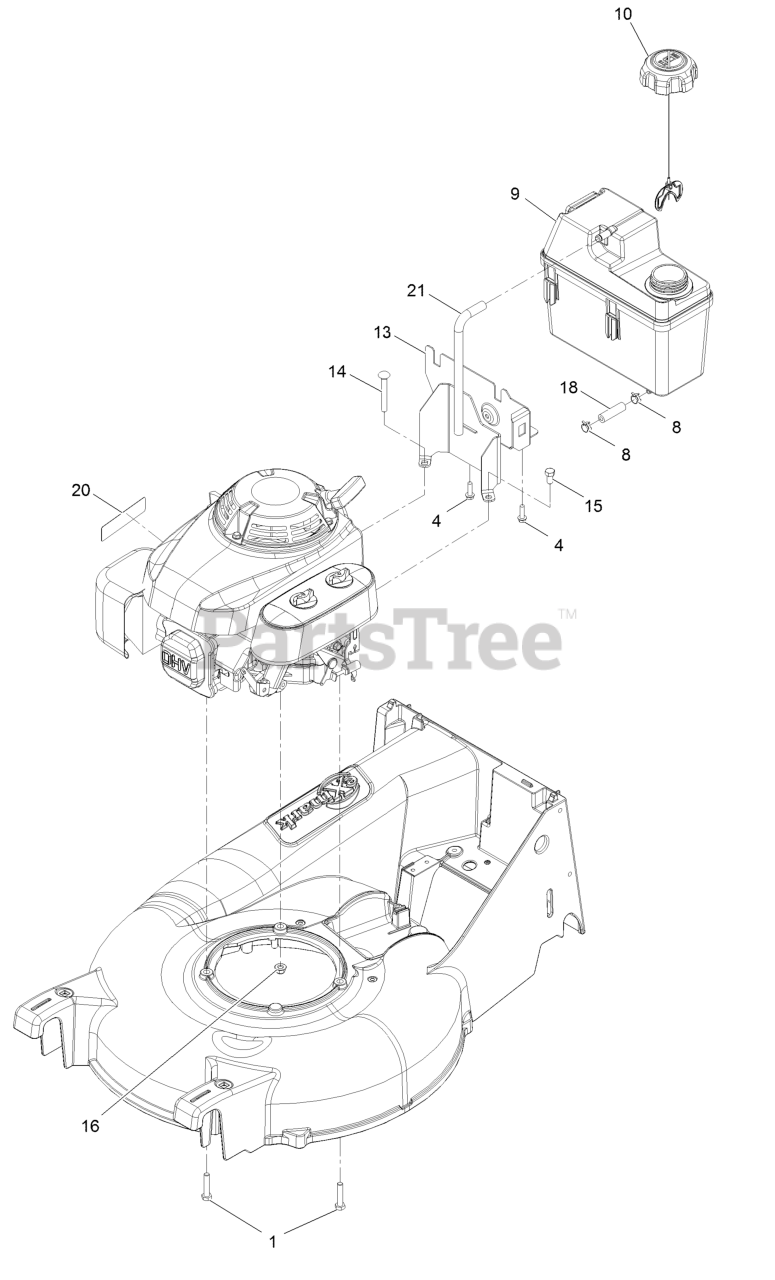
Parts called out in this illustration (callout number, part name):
1	Screw-HH 5/16-24 X 1 1/2
4	Screw-HWH 1/4-10 X .82 Plastite
8	Clamp-Hose
9	Tank-Fuel
10	Cap-Fuel
13	Asm-Bracket
14	Bolt-Carriage 5/16-18 X 2 1/2
15	Screw-HH 5/16-24 X 5/8
16	Nut-Nyloc 5/16-18 Flg
18	Hose-Fuel
20	Decal-Arrester, Spark
21	Hose-Vent, Canister
